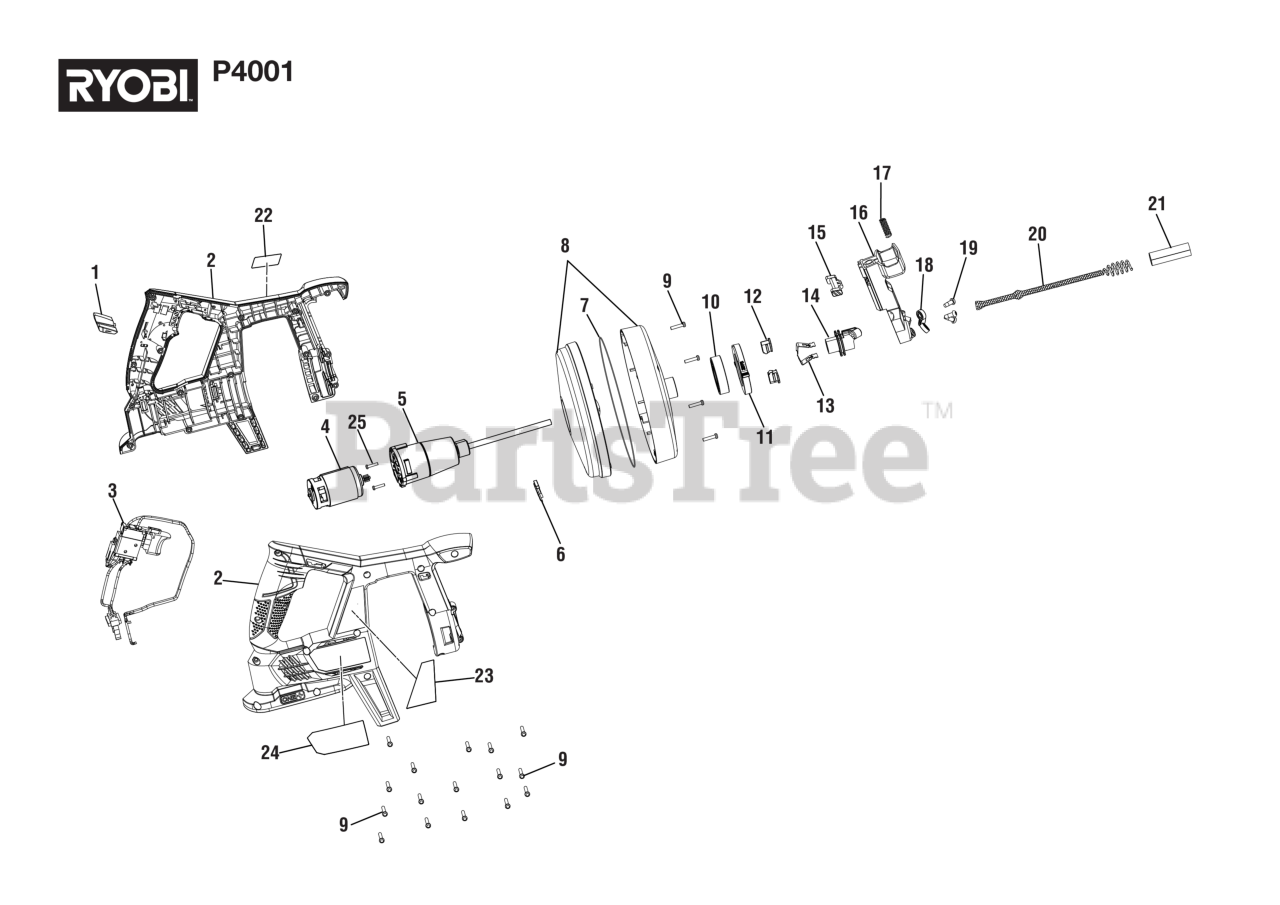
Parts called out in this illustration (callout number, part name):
1	Direction of Rotation Selector (Forward/Reverse/Center Lock)
2	Motor Housing Assembly
3	Switch Assembly
4	Motor Assembly
5	Gear Box Assembly
6	Drain Tab (Rubber Seal)
8	Drum Assembly
9	Screw (M3.5 x 14 mm, T10 Tox Pan Hd.)
10	Ball Bearing (6005 2Z)
11	Lock Ring
12	Slide Block
13	Lock Spring Plate
14	Cable Tube
15	Auto-Feed Lock
17	Compression Spring
18	Ball Bearing (605-2RS)
19	Screw (M5 x 12 mm, T25 Torx CH Hd.)
20	Snake Cable (Auger)
22	Logo Label
23	Data Label
24	Warning Label
25	Screw (M3 x 6 mm, Pan Hd.)
